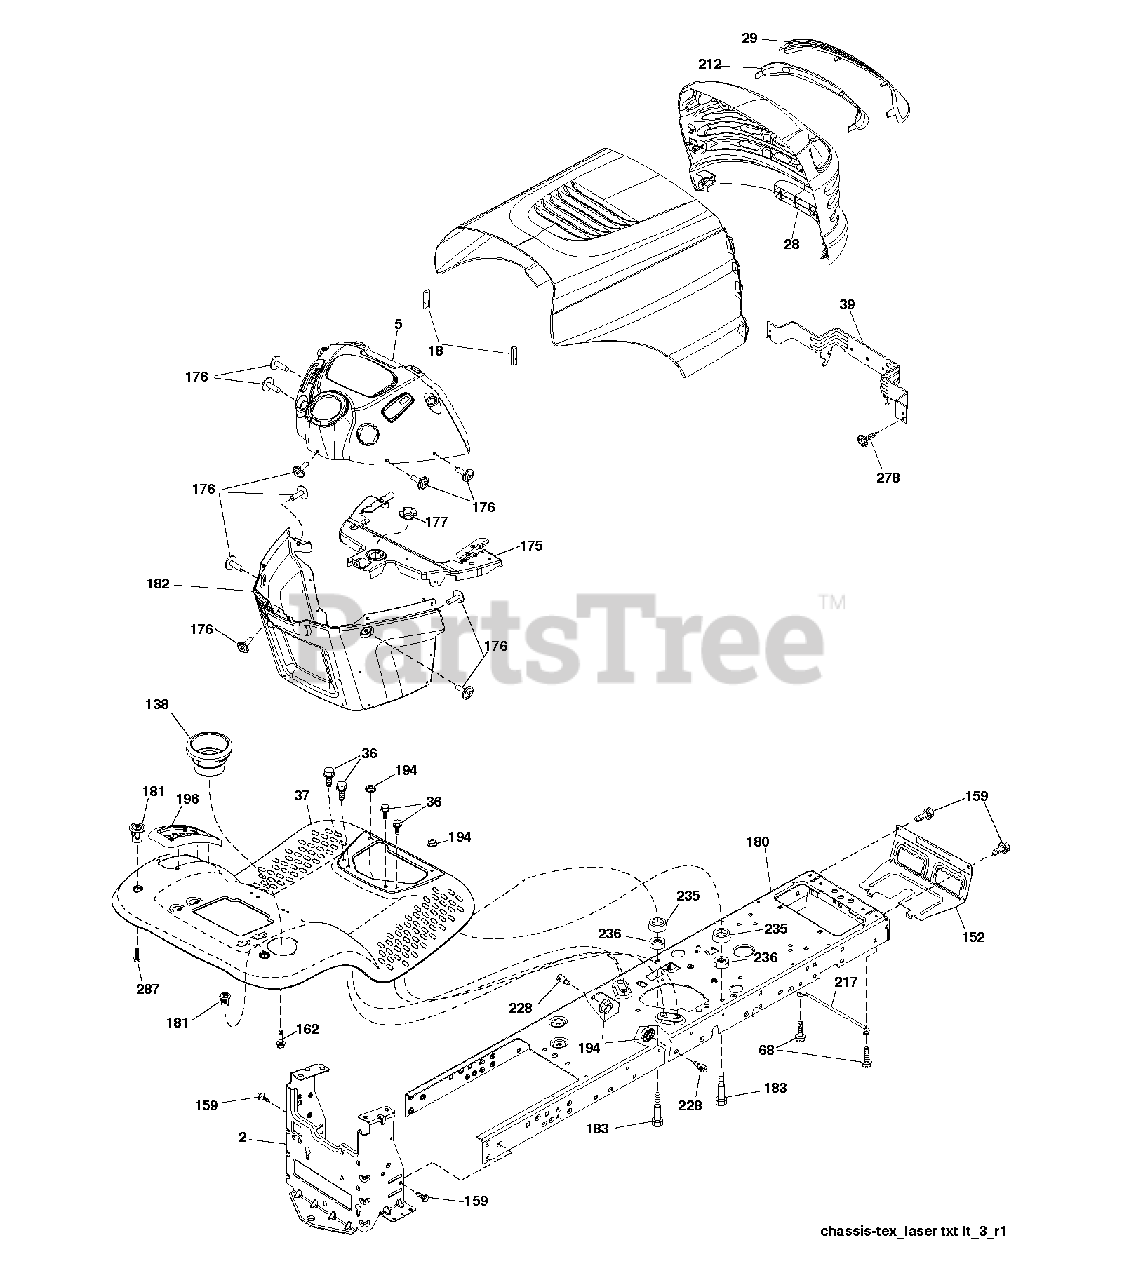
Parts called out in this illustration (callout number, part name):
2	DRAWBAR.1PC.NSTL
5	DASH.P/L.TEX.CBL.CL.N/CHK.BLAC
18	BUMPER.HOOD.LARGE.1.75"
29	LENS.LASER LT.CLEAR.BAR
36	SCREW 5/16"
37	FENDER.TLT.FS.W/CPH.550
39	BRACKET PIVOT
58	DRAWBAR UPPER 2PC SMALL FENDER
68	SCREW LT
138	CUPHOLDER.TL.TEX.BLACK
152	SHIELD.BROWNING/DEBRIS
159	SCREW, 3/8-16X3/4
162	SCREW.HI-LO.CONSOLE
175	CROSSMEMBER.LT
176	SCREW.#10-24X5/8.RN.QU
177	BUSHING STEERING
180	CHASSIS.STAMPING.LT/GT
181	FEND/FTRST.PCH.CPH.NFW
182	DASH.LOWER.LT.CCS
183	BOLT.5/16-18X1-1/4 FULL.THREAD
194	NUT LOCK HEX FLANGE 5/16-18
217	ROD.PIVOT.HOOD
228	STUD.FASTNER.W/ANTI-ROTATE
235	SPACER FENDER
236	NUT.CENTERLOCK.5/16-
278	SCREW.#10 X 0.750.BOS (2 2)
287	SCREW 1/4X20
